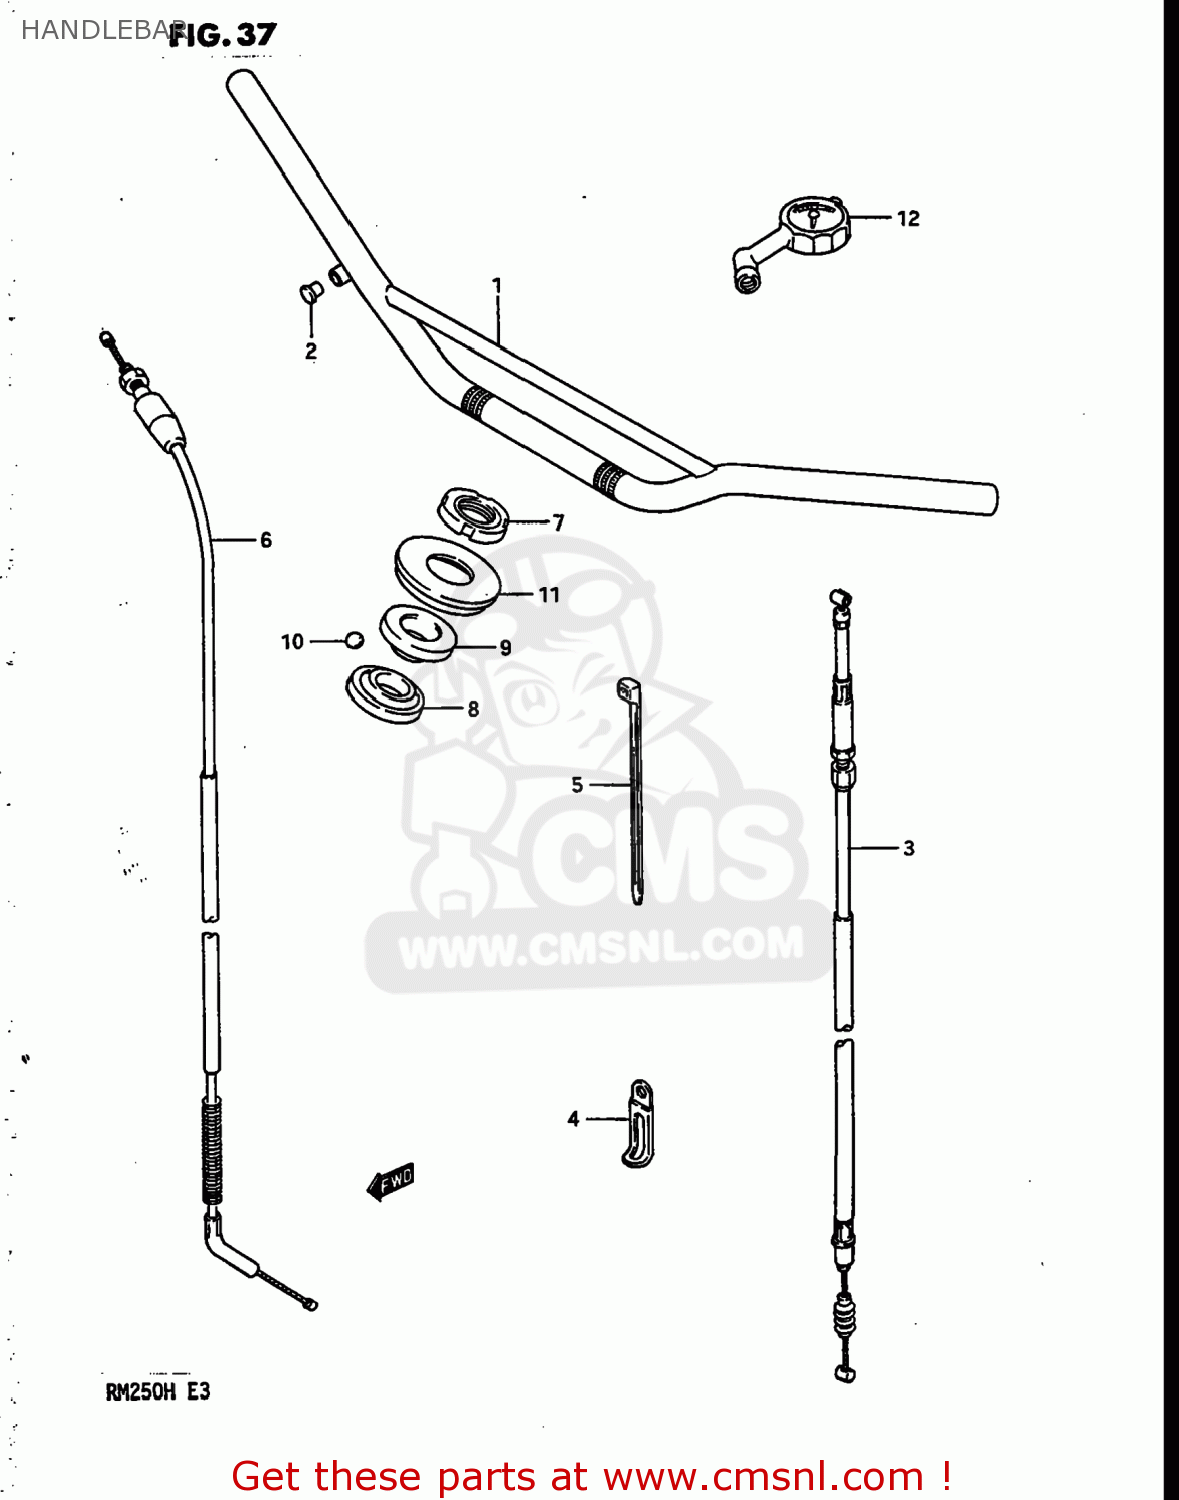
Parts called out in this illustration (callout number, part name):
1	HANDLEBAR
2	CAP(OD:14)
3	CABLE ASSEMBLY,CLUTCH
4	CLAMP L:35
5	CLAMP(L:145)
6	CABLE ASSEMBLY,THROTTLE
7	NUT,STEERING STEM
8	RACE,STEERING INNER (SUJ)
9	RACE,STEERING,OUTER,UPPER
10	BALL
11	SEAL,STEERING UPR DUST
12	GAUGE ASSY,AIR PRESSURE
